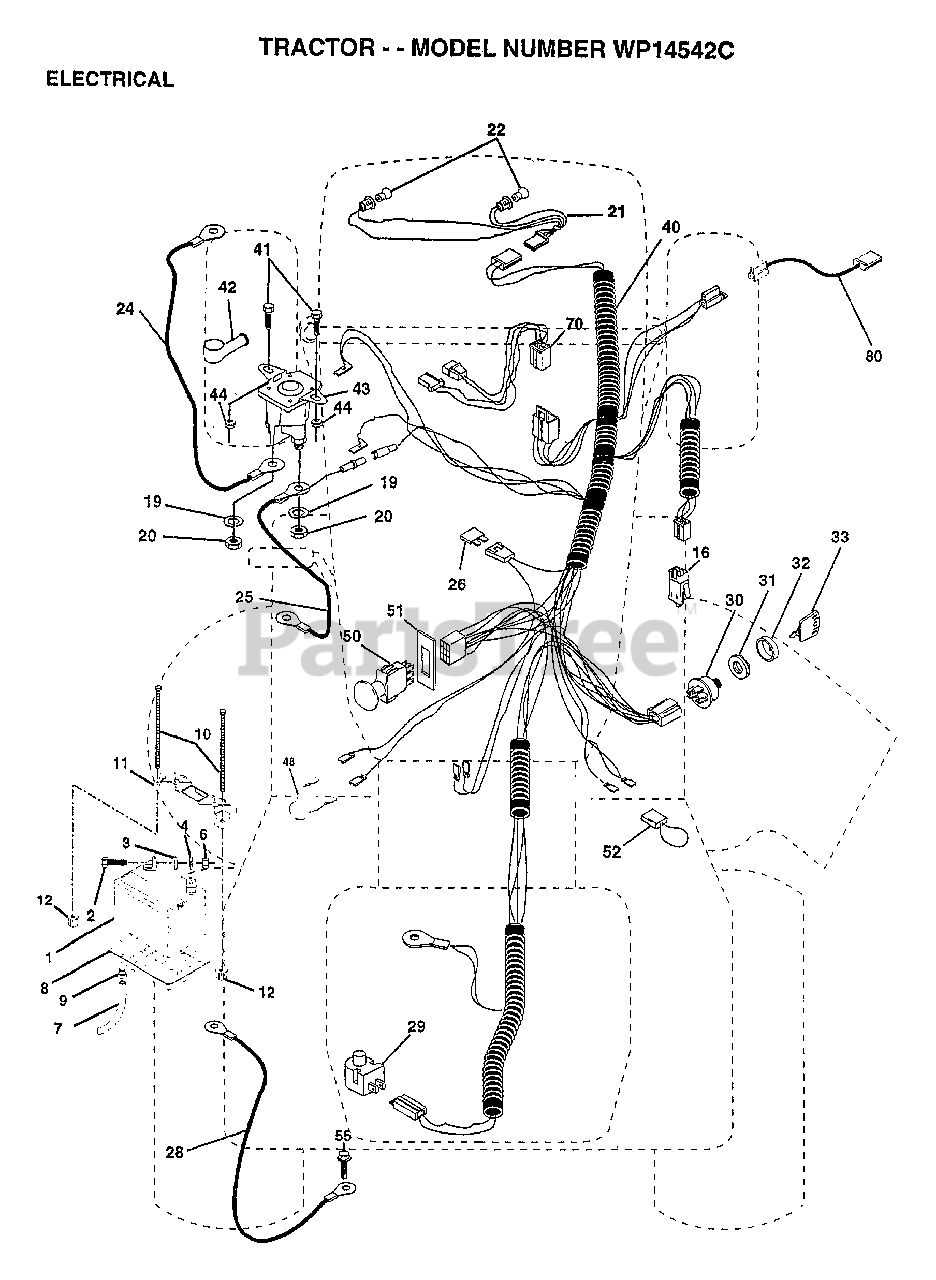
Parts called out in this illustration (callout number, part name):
2	BOLT LT
3	WASHER
4	LOCKWASHER
7	"DRAIN TU T, BATT"
8	"TRAY T, BATTERY"
9	HOSE CLAMP T
11	HOLDDOWN BATTERY
16	SWITCH INTERLOCK
20	NUT
21	HARNESS.ASM.HDLIG
22	HEADLAMP BULB
24	CABLE.6GA.22W/16W
25	CABLE.BTRY.6GA.RD
26	FUSE HYT
29	CABLE.GRND.6GA.21
29	SWITCH SEAT
30	SWITCH IGN 4POS
31	NUT IGNITION
32	COVER KEY SWITCH
33	KEY
40	HARNESS IGNITION
41	BOLT HXHD FIN
44	NUT HXKEP 1/4X20
48	ADAPTER AMMETER
50	SWITCH, PTO 3PDT BLACK DELTA 96
51	RING RETAIN PTO
52	PROTECTION LOOP
55	SCREW LT
70	HARNESS.ENG.DUAL
80	HARNESS.CLUT.EVX.
